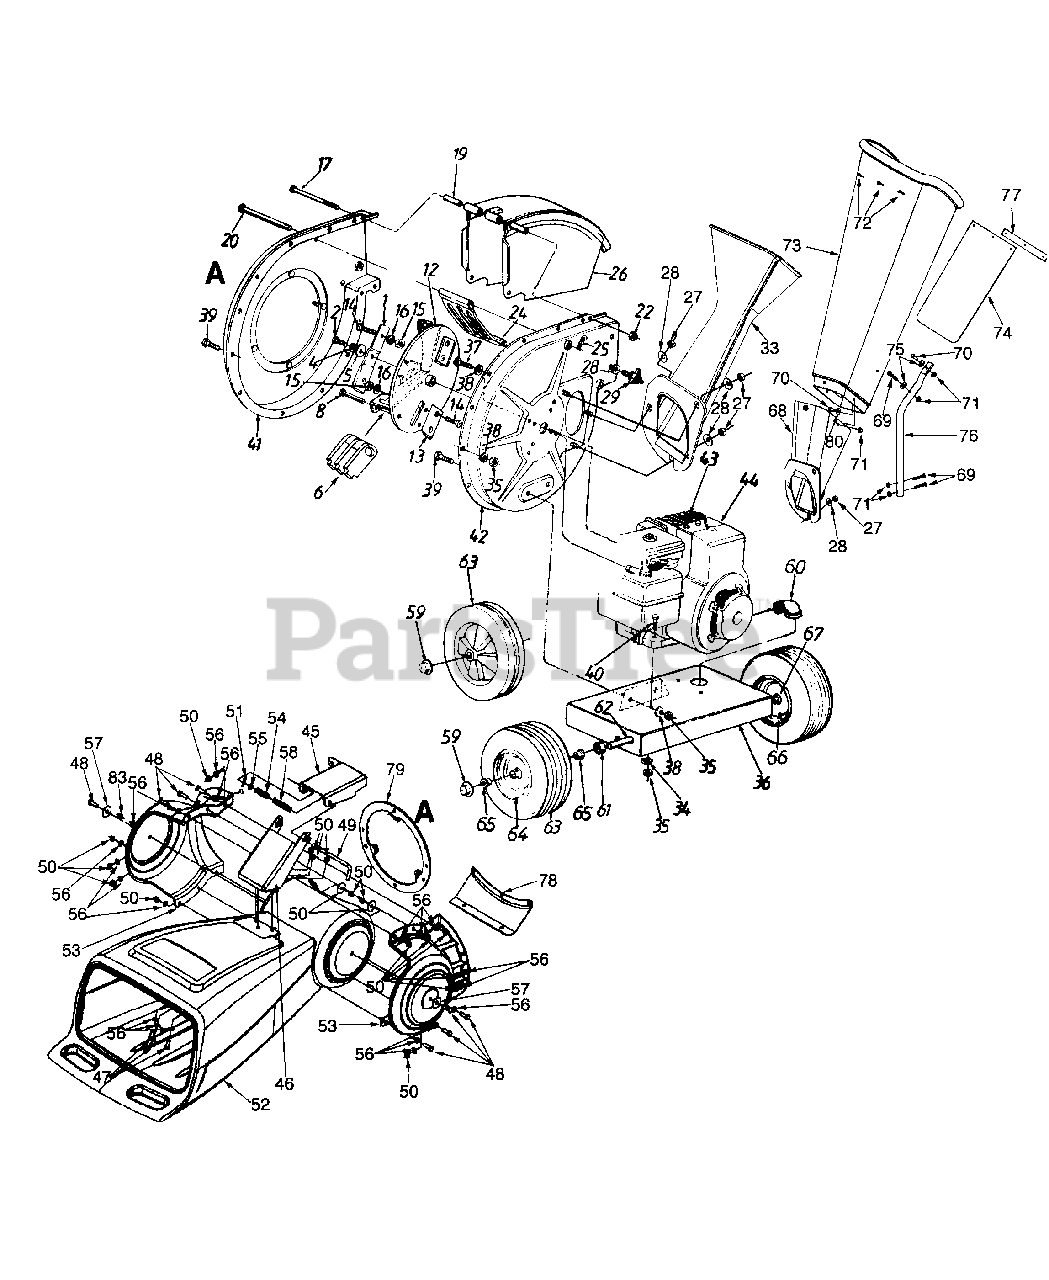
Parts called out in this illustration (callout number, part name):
1	Blade
2	Hex Patch Bolt 3/8-24 x 2.25" (Gr. 8)
4	L-Wash. 3/8" I.D. H.D.
5	Fl-Wash. .406" I.D. x 1.25" O.D. Hdn.
6	Flail Blade
8	Clevis Pin .496" Dia.
12	Impeller Ass'y. Comp.
13	Chipper Blade
14	Flat Hd. Scr. 5/16-24 x .75: Lg.
15	Hex Top L-Nut 5/16-24 (Gr. 5)
16	L-Wash. 5/16" I.D.
17	Hex Bolt 1/4-20 x 3.75" Lg.
19	Chute Hinge Spacer 1.66" Lg.
20	Clevis Pin .5" Dia. x 4.62" Lg.
22	Hex Ctr. L-Nut 1/4-20 Thd.
25	Internal Cotter Pin 3/8" Dia.
27	Hex Nut 5/16-18 Thd. (Gr. 5)
28	Bell-Wash. .345 I.D. x .88"
29	Hand Knob
34	Spec. L-Wash. 5/16" I.D.
35	Hex Nut 5/16-18 Thd. (Gr. 5)
37	Hex Bolt 5/16-24 .75" Lg.
38	L-Wash. 5/16" I.D.
39	Hex Bolt 5/16-18 x .75" Lg. (Gr. 5)
40	Hex Bolt 5/16-18 x 1.75" Lg.
43	Spark Plug Boot
44	Engine
47	Hex Bolt 5/16-18 x .75" Lg. (Gr. 2)
48	Hex Bolt 5/16-18 x 1.0" Lg. (Gr. 5)
49	Lock Rod
50	Hex L-Nut 5/16-18
51	Internal Cotter Pin .072 x 1.12 Lg.
52	Hopper
53	Collar--Hopper
54	Compression Spring
55	Flat Wash. 3/8 x .620 x .033
56	Flat Wash. 330 x .630 x .06
57	Flat Wash. .320 I.D. x 1.25 O.D.
58	Spacer .382 I.D. x .50 O.D. x 1.12
59	Push Cap 5/8" Dia. Rod
60	Drain Elbow
61	Spacer .64 I.D. x .38" Lg.
62	Shredder Axle
63	Wheel Ass'y. Comp.
66	Air Valve
67	Grease Fitting
70	Hex Bolt 1/4-20 x 0625
71	Lock Nut 1/4-20
72	Pop Rivet
73	Chipper Chute
74	Chute Flap
75	Flat Wash. .28 I.D.
77	Flat Strip
